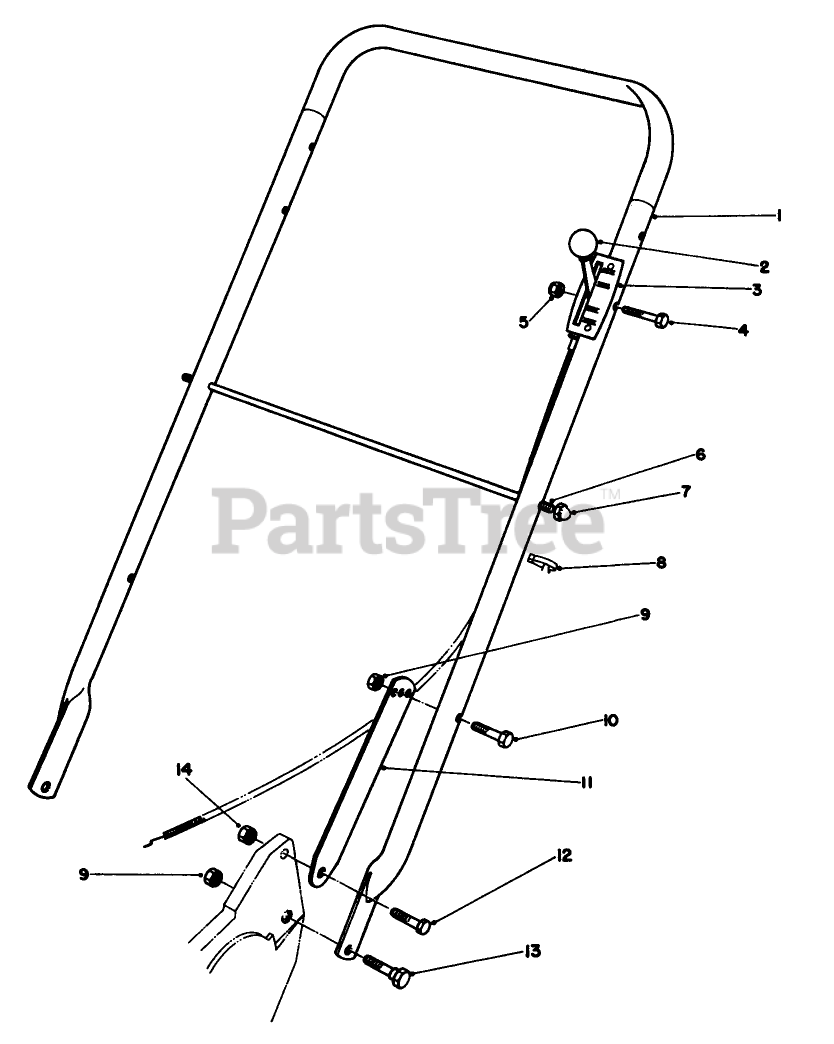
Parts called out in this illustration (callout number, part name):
2	KNOB-CONTROL
4	SCREW-HH
5	NUT-LOCK, NI
6	ROD-SUPPORT, BAG
7	NUT-CAP
9	NUT-LOCK, CONE
10	SCREW-HH
12	SCREW-HH
13	SCREW-SHOULDER
14	NUT-LOCK, NI
